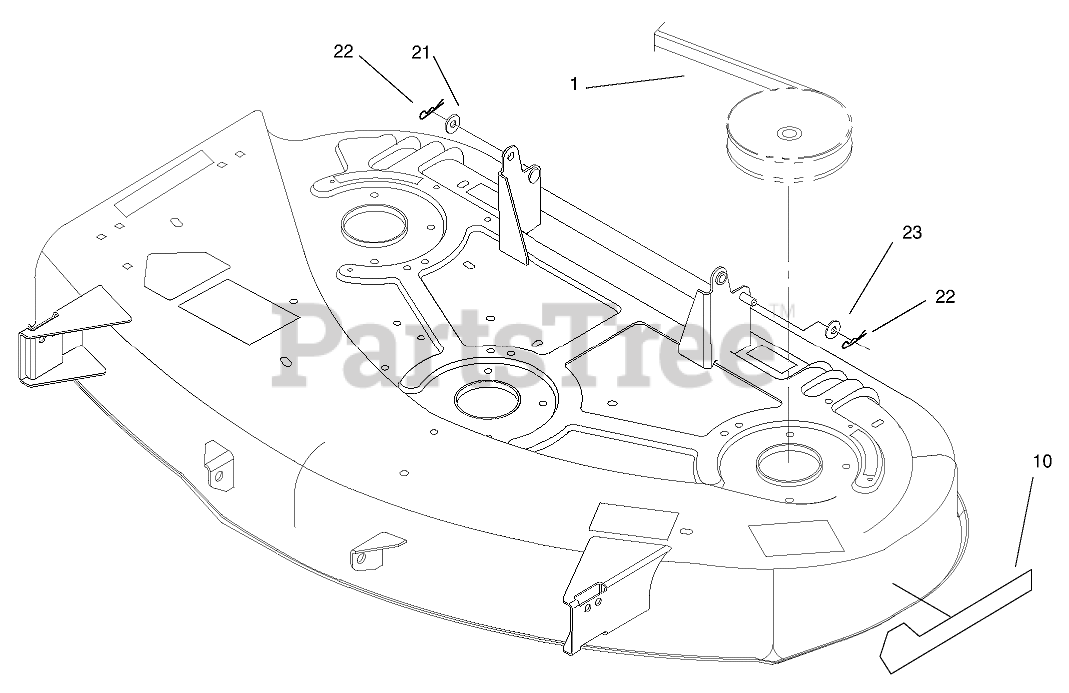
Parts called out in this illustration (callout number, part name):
1	V BELT-DECK
10	DECAL - RECYCLER, 44"
21	WASHER-FLAT
22	PIN-COTTER
23	WASHER-HARDENED
